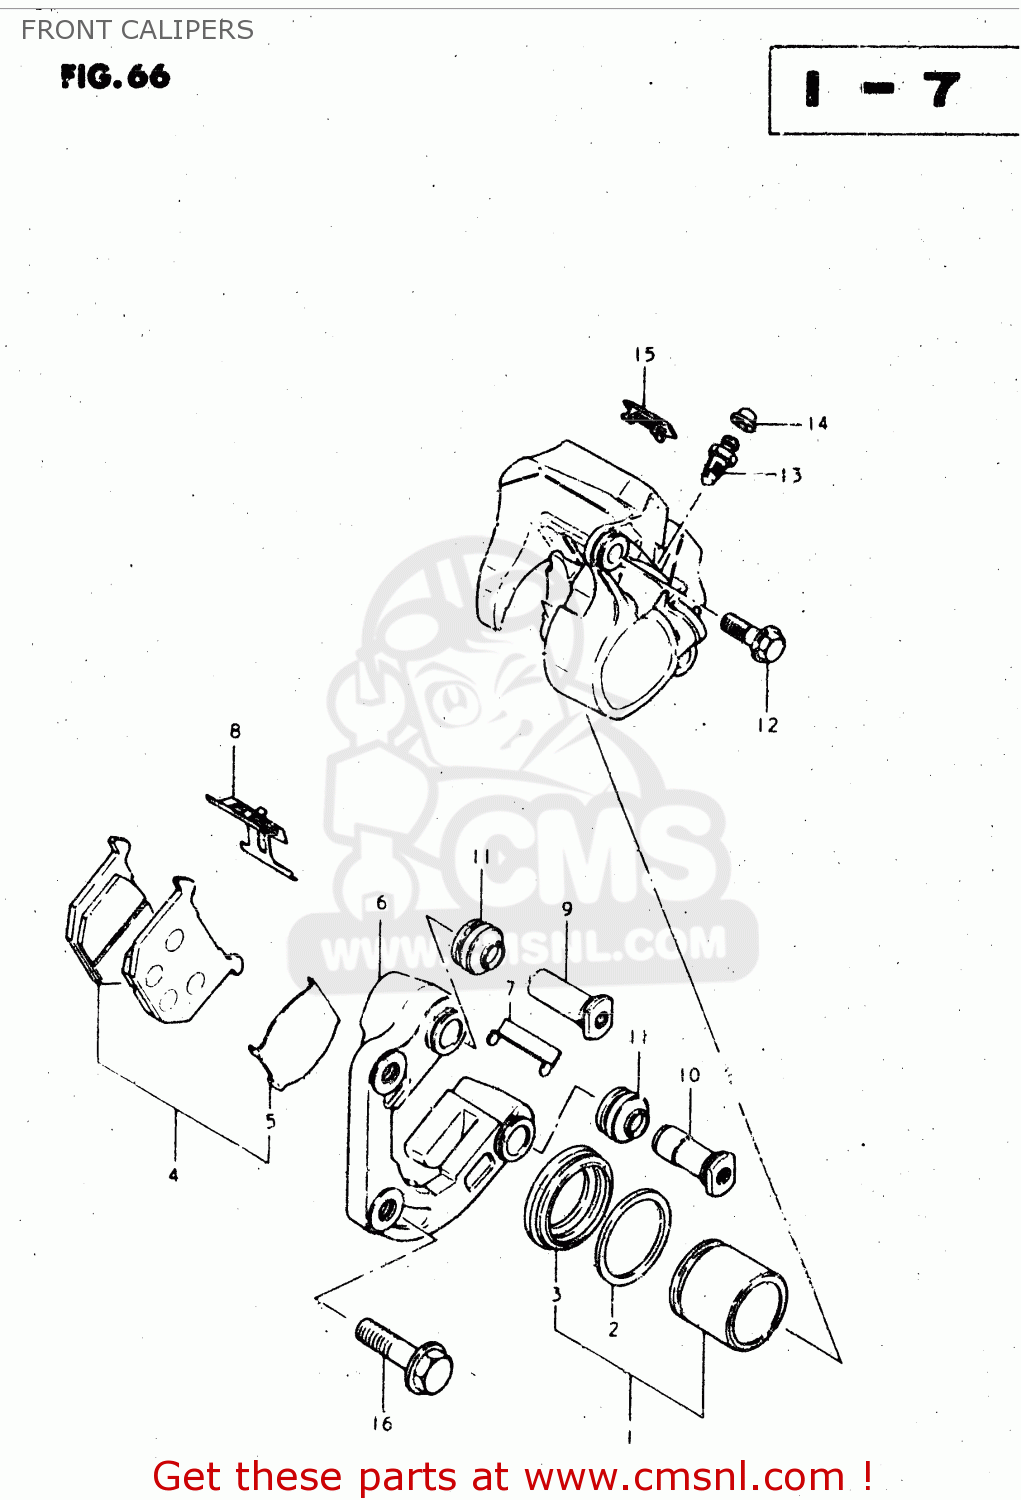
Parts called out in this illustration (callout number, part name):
1	PISTON SET
2	SEAL,FR CALIPE
3	BOOT,PISTON
4	PAD SET (MCA)
5	SHIM,PAD
6	CARRIER,CALIPER,LEFT
7	GUIDE,PAD
8	SPRING,PAD
9	AXLE NO.1
10	AXLE NO.2
11	BOOT,AXLE
12	BOLT,CALIPER HOUSING
13	BLEEDER
14	CAP,BREATHER
15	COVER,INDICATOR
16	BOLT(10X37)
